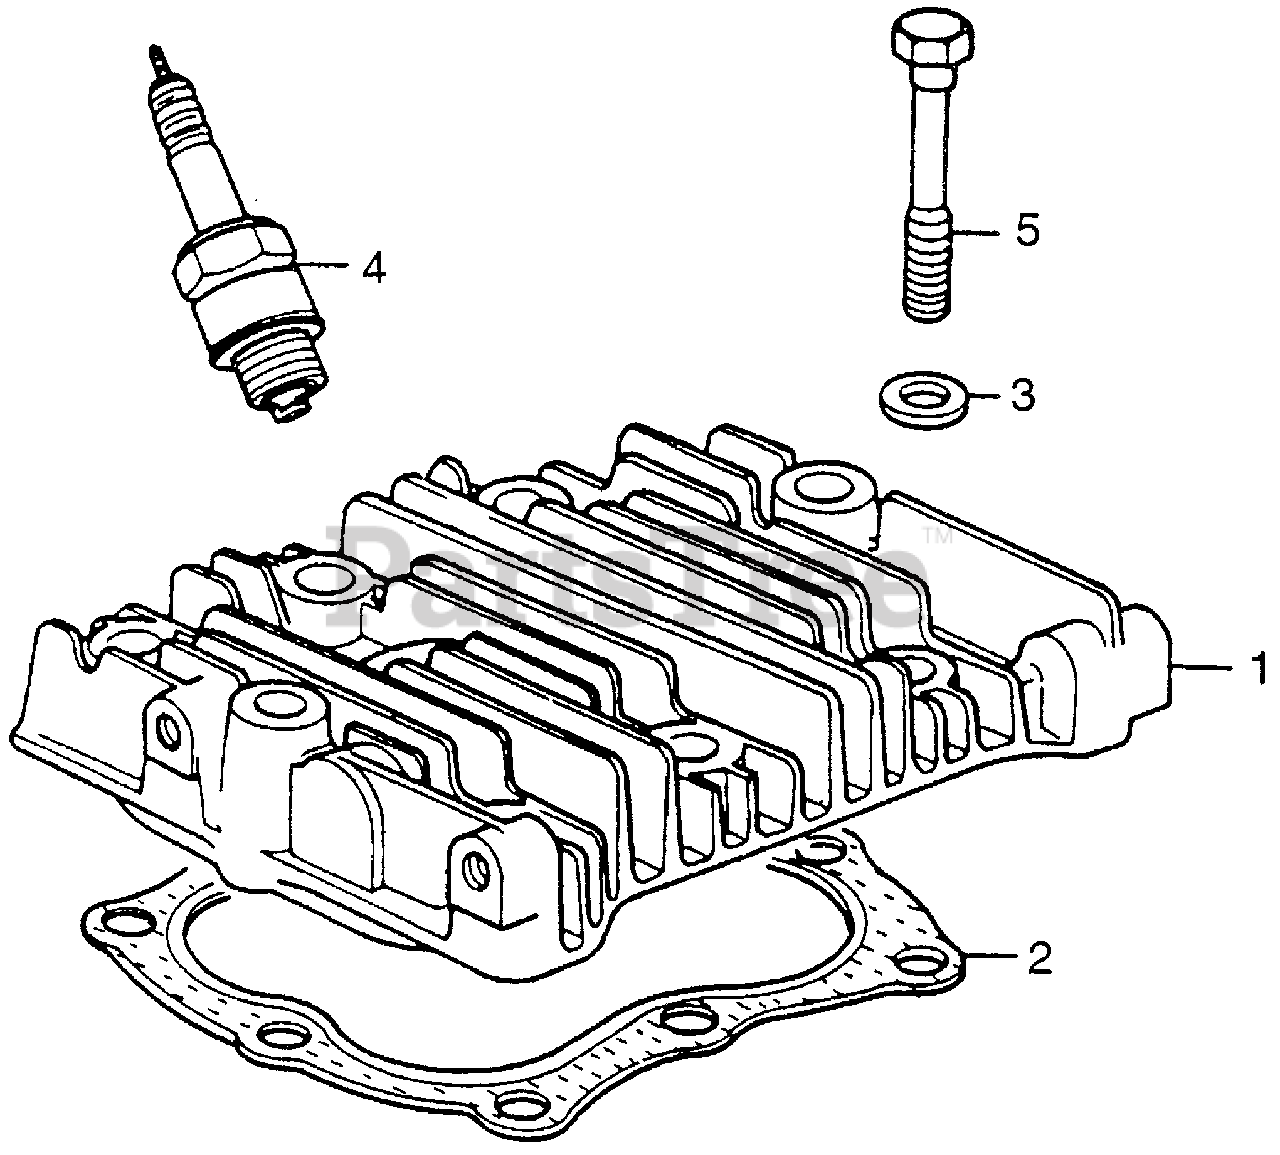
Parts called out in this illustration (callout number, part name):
1	CYLINDER HEAD
2	GASKET, CYLINDER HEAD
3	WASHER, HEAD (8MM)
4	SPARK PLUG (B6HS) (NGK)
5	BOLT, HEX. (8X45)
